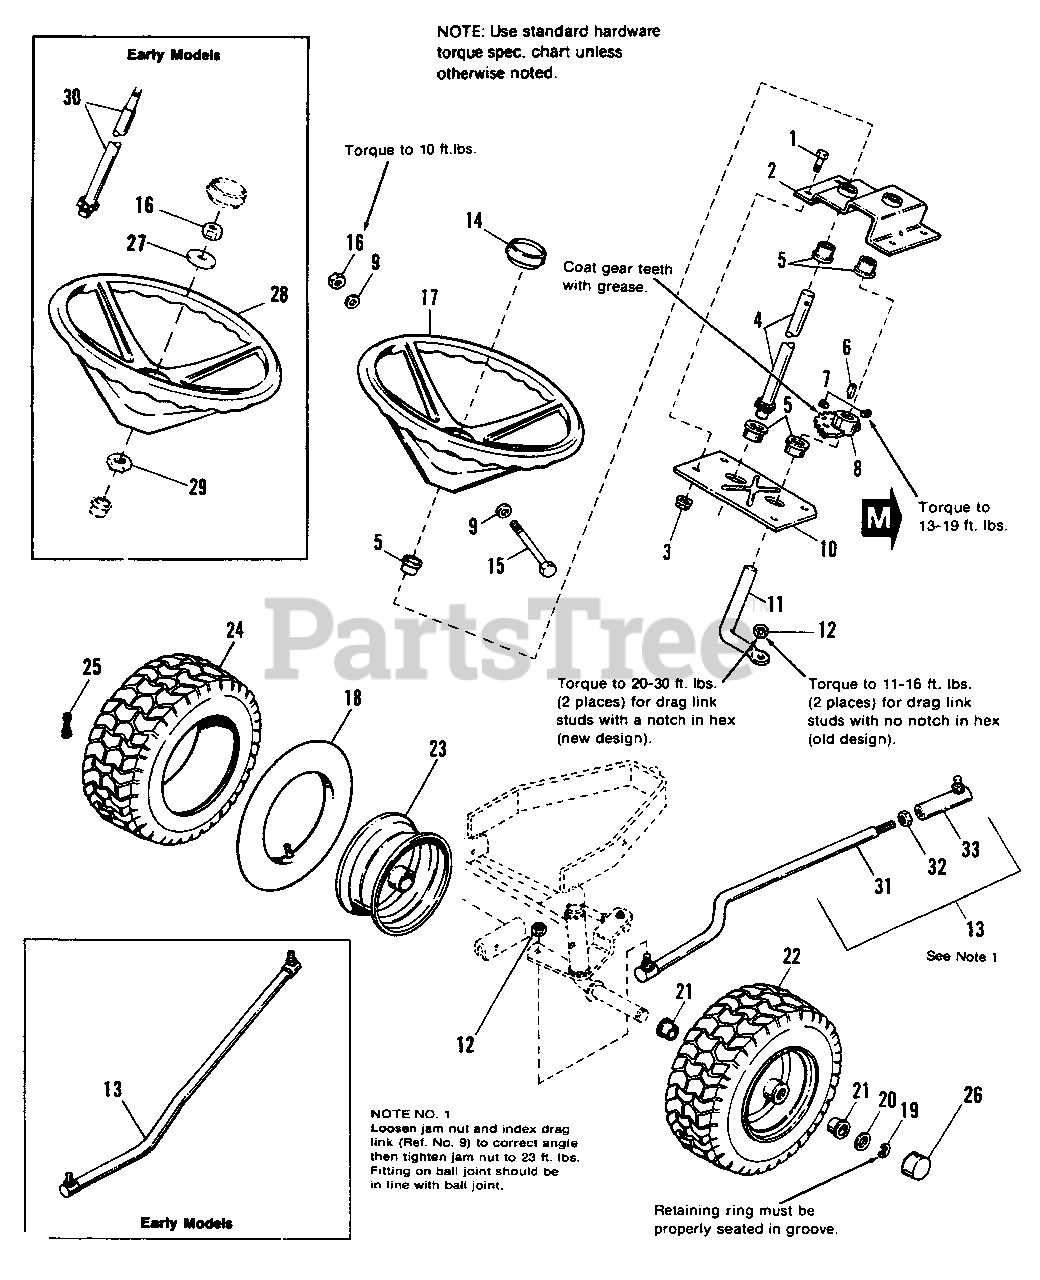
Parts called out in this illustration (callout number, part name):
1	CAPSCREW, 5/16-18 x 3/4
2	TOP PLATE, Steering
3	LOCKNUT, Flange Whiz, 5/16-18
4	SHAFT ASSY, Steering
7	SETSCREW, 5/16-18 x 1/2, Gr. 8
8	GEAR, Steering
9	WASHER, Plain, 5/16
10	BASE PLATE, Steering
11	ROD, Steering (Used on Mfg. No 1690840 from serial no. 1327 thru 3319; and on Mfg. No. 1690843 after serial no. 1498.)
11	ROD, Steering (Used on Mfg. No. 1690840 before serial no. 1327 and on Mfg. No. 1690843 before serial no. 1499.)
11	ROD, Steering (Used on Mfg. No. 1690840 after serial no. 3319.)
12	LOCKNUT, Center, 3/8-24
13	LINK, Drag (Used on all Mfg. No. 1690843, and on 1690840 before serial no. 3320) (One piece assy.)
13	LINK ASSY, Drag (Used on all Mfg. No. 1690840 after serial no. 3319) (Incl. Ref. Nos. 32, 32, 33)
14	CAP, Steering Wheel
15	BOLT, Hex, 5/16- 18 x 3- 1 /2
16	LOCKNUT, Hex, 5/16-18
17	WHEEL, Steering
18	TUBE (Service Only See Note Below)
19	"E" RING, Ext., 3/4
22	WHEEL & TIRE ASSY., 13 x 5.00-6 (Used on Mfg. No. 1690840)
22	WHEEL & TIRE ASSY., 15 x 6.00-6 (Used on Mfg. No. 1690843)
23	WHEEL, w/o Bearings (Used on Mfg. No. 1690840)
23	WHEEL, w/o Bearings (Used on Mfg. No. 1690843)
24	TIRE, 13 x 5.00-6, Tubeless Turf Tread (Used on Mfg. No. 1690840)
24	TIRE, 15 x 6.00-6, Carlisle (Used on Mfg. No. 1690843)
24	TIRE, 15 x 6.00-6, Goodyear (Used on Mfg. No. 1690843)
25	STEM, Valve
26	CAP, Hub, Threaded
27	WASHER, Compression
28	WHEEL, Steering (Includes Ref. No. 29)
29	WASHER, Hex
30	SHAFT, Steering
32	NUT, Jam 3/8-24 UNF-2B
33	BALL JOINT ASSY.
